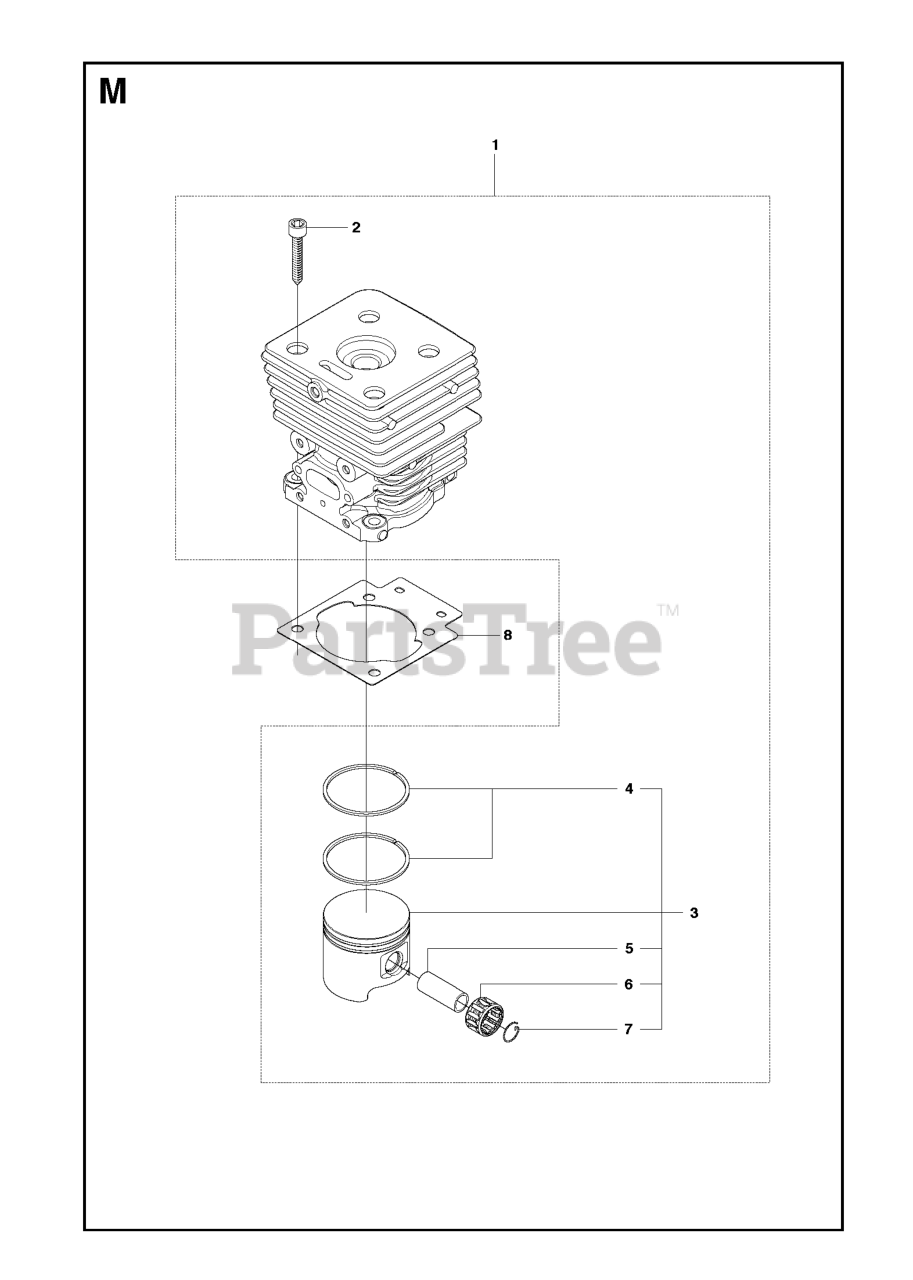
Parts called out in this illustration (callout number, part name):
1	CYLINDER ASSY
2	SCREW
3	PISTON ASSY D41 SPARE PART
4	PISTON RING D41X1.7X1.2
5	PISTON PIN 10X7X32
6	SUPPORT BUSHING
7	LOCKING RING
8	GASKET CYLINDER
